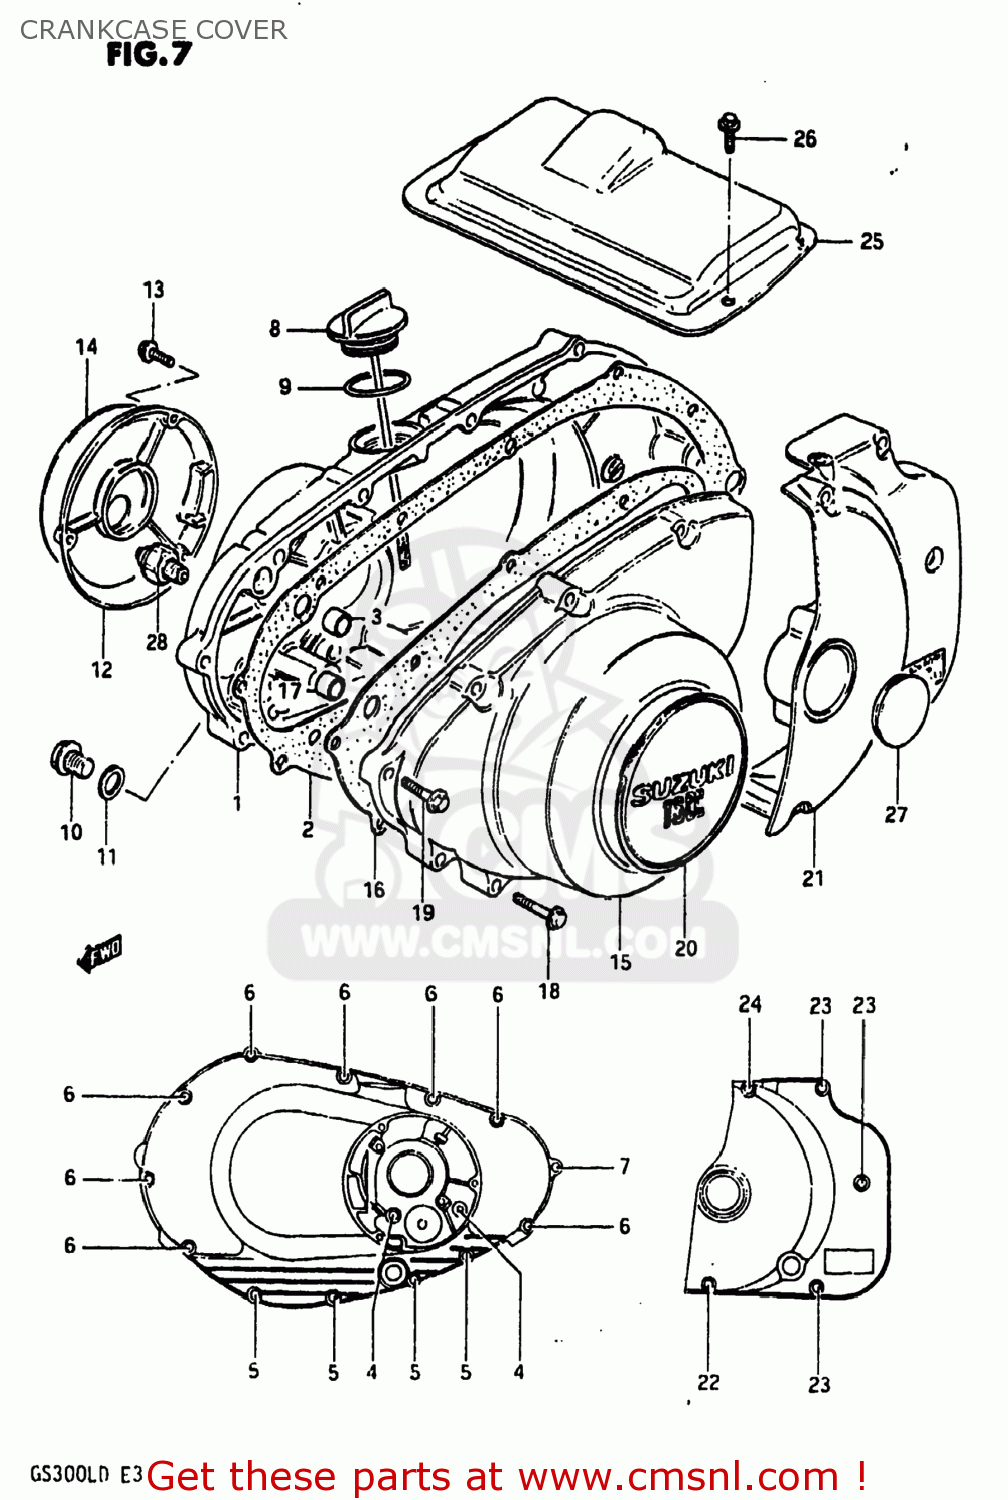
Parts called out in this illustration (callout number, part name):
1	COVER,CLUTCH
2	GASKET,CLUTCH COVER (MCA)
3	PIN
4	BOLT (6X50)
5	BOLT
6	BOLT (6X35)
7	BOLT
8	GAUGE,OIL LEVEL
9	O-RING
10	PLUG (14X12)
11	GASKET(14X19.2X2) (NAS)
12	COVER,CONTACT BREAKER
13	BOLT (5X20)
14	EMBLEM
15	COVER,MAGNETO
16	GASKET,MAGNETO COVER (MCA)
17	PIN
18	BOLT (6X30)
19	BOLT
20	EMBLEM
21	COVER,ENGINE SPROCKET
22	BOLT
23	BOLT (6X40)
24	BOLT (6X30)
25	COVER,STARTER MOTOR
26	BOLT (5*8)
27	CAP(OD:36)
28	SWITCH ASSEMBLY
